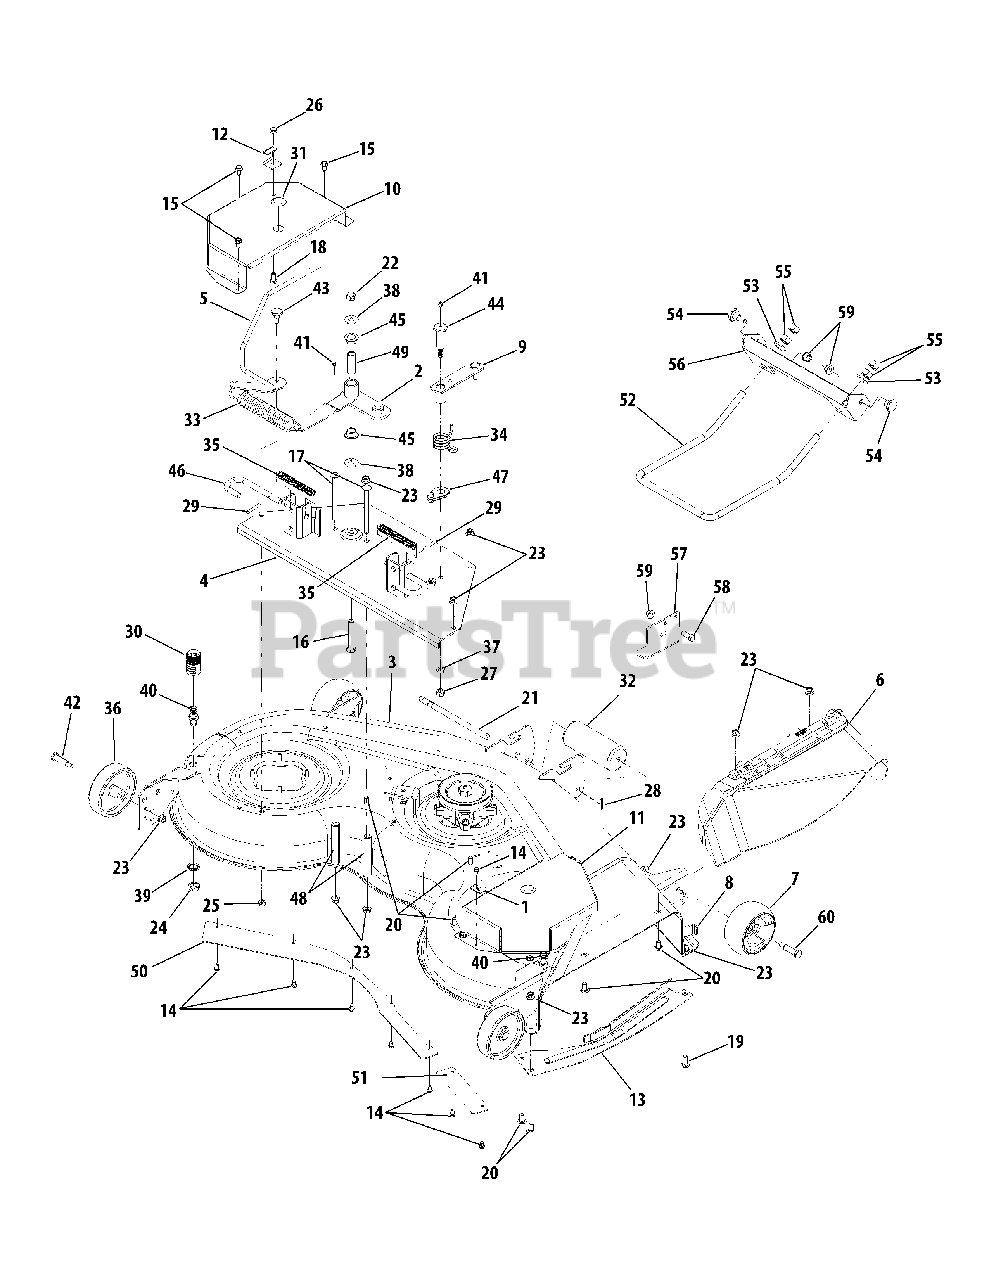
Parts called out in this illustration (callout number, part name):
1	Hook, Retainer
2	Arm, Idler
4	Plate Assembly, Deck Mounting
5	Handle, Tension
6	Chute Assembly
7	Wheel, Gauge Ball
8	Bracket, Chute Deflector Stop
9	Arm, Idler
10	Shield, Spindle LH
11	Shield, Spindle RH
12	Bracket, Handle Stop
13	Guard, Finger
14	Screw, Hex Wash. Hd Tapp , 1/4-20 x .5
15	Screw, Hex Wash. Hd Tapp, 5/16-12 x .75
16	Screw, Hex Cap, 1/2-20 x 3.0 GR8
17	Screw, Carriage, 3/8-16 x 5.0 GR5
18	Screw, Cap, 5/16-18x .75 GR5
19	Bolt, Carriage, 3/8-16 x 1.0 GR5
20	Bolt, Carriage, 3/8-16 x .75 GR5
21	Pin, Roller, 1/2 Dia x 7.31
22	Nut, Hex Lock, 1/2-20
23	Nut, Hex Flange Lock, 3/8-16 GRF
24	Nut, Hex M16-1.5
25	Nut, Hex Ctr. Lock, 3/8-16 GRB
26	Nut, Hex Flange Lock, 5/16-18 GR5
27	Nut, Hex, 7/16-14 GR2
28	Pin, Cotter, 3/32 Dia x 1.25
29	Pin, Spirol, 3/16 x .75
30	Adapter, Water Nozzle
31	Plug, Button
32	Roller, Front
33	Spring, Extension, 1.25 OD x 7.2
34	Spring, Torsion
35	Spring, Compression
36	Wheel, Gauge
37	Washer, Lock, 7/16
38	Washer, Flat, .5 x 1.25 x .1
39	Washer, Lock
40	Nozzle, Deck Water
41	Fitting, Lube, 3/16 Drive
42	Bolt, Shoulder, .498 x 1.53:3/8-16
43	Bolt, Shoulder, .500 Dia x .434
44	Bolt, Shoulder, .68 x 2.11:7/ 16-14
45	Bearing, Flange
46	Pin, Mower Support
47	Retainer, Spring
48	Spacer, .405 x .75 x 4.312
49	Spacer, .5 x .75 x 2.07
52	Rod, Front Lift
53	Washer, Flat, .531 x 1.062 x .134 HT
54	Bolt, Shoulder, .50 Dia. x .494 Lg
55	Nut, Hex, 1/2-13 Gr5
56	Bracket, Front Lift
57	Bracket, Up-Stop
58	Screw, Hex Cap, 3/8-16 x 1.0 Gr5
59	Nut, Flange Lock, 3/8-16 GrF
60	Bolt, Shoulder, .496 x 2.5:3/8-16
